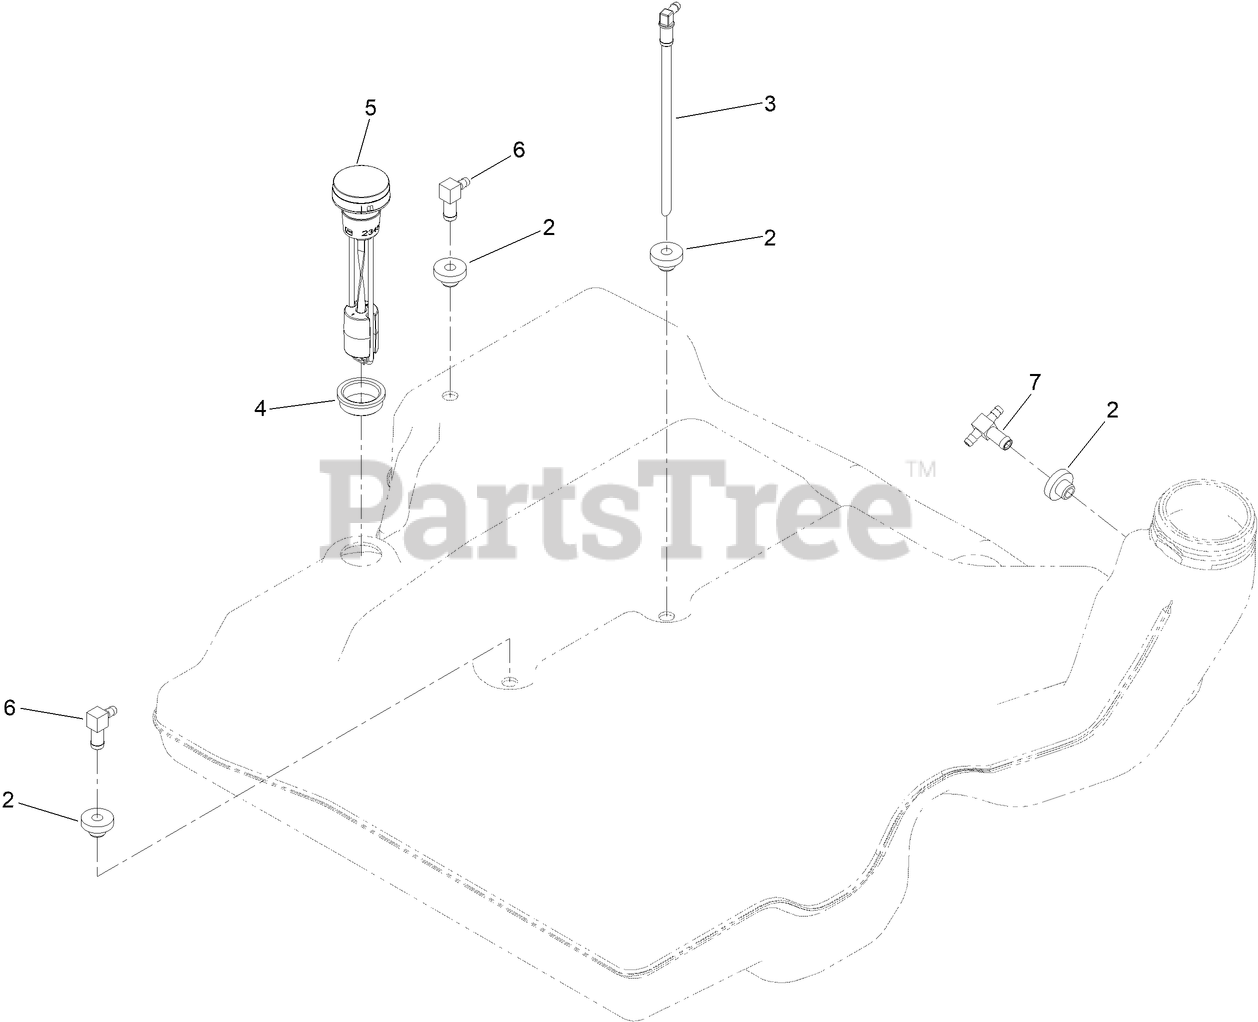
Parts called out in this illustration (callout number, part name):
2	BUSHING
3	CONNECTOR ELBOW-90 DEG
4	GROMMET-FUEL
5	GAUGE-FUEL
6	FITTING-90 DEG
7	FITTING-TEE
